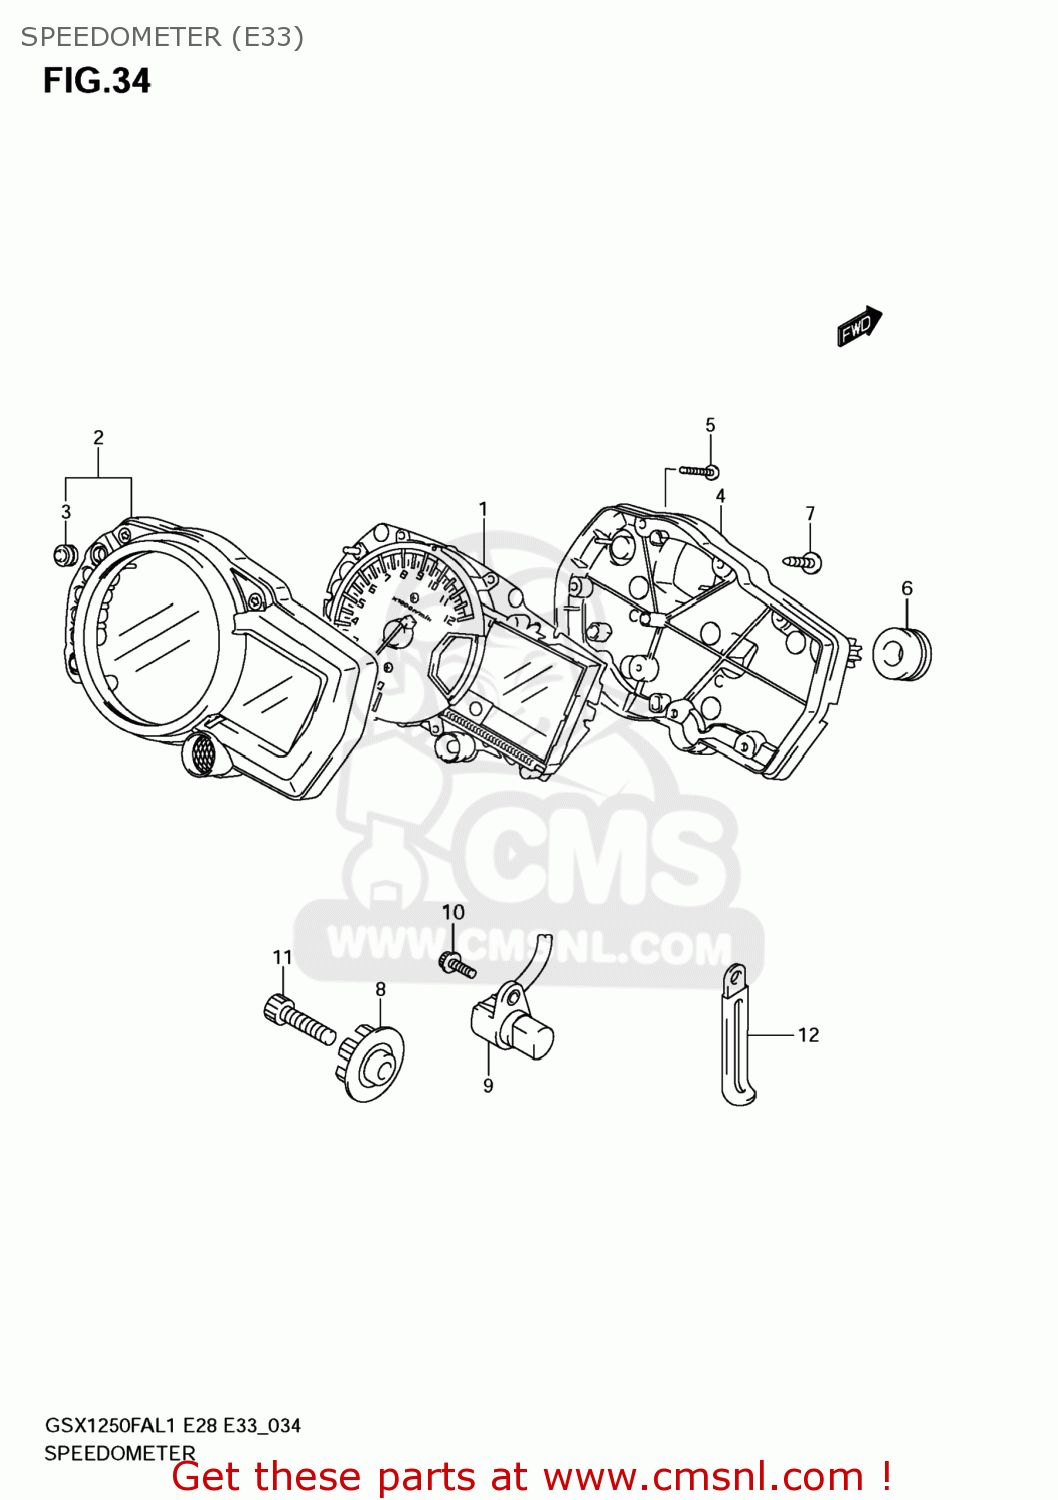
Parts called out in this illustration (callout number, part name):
1	SPEEDOMETER
2	CASE,UPR
3	RUBBER,SWITCH
4	CASE,LWR
5	SCREW(3X16)
6	CUSHION
7	SCREW
8	ROTOR,SPEED
9	SENSOR,SPEED
10	BOLT
11	BOLT
12	CLAMP(L:45)
